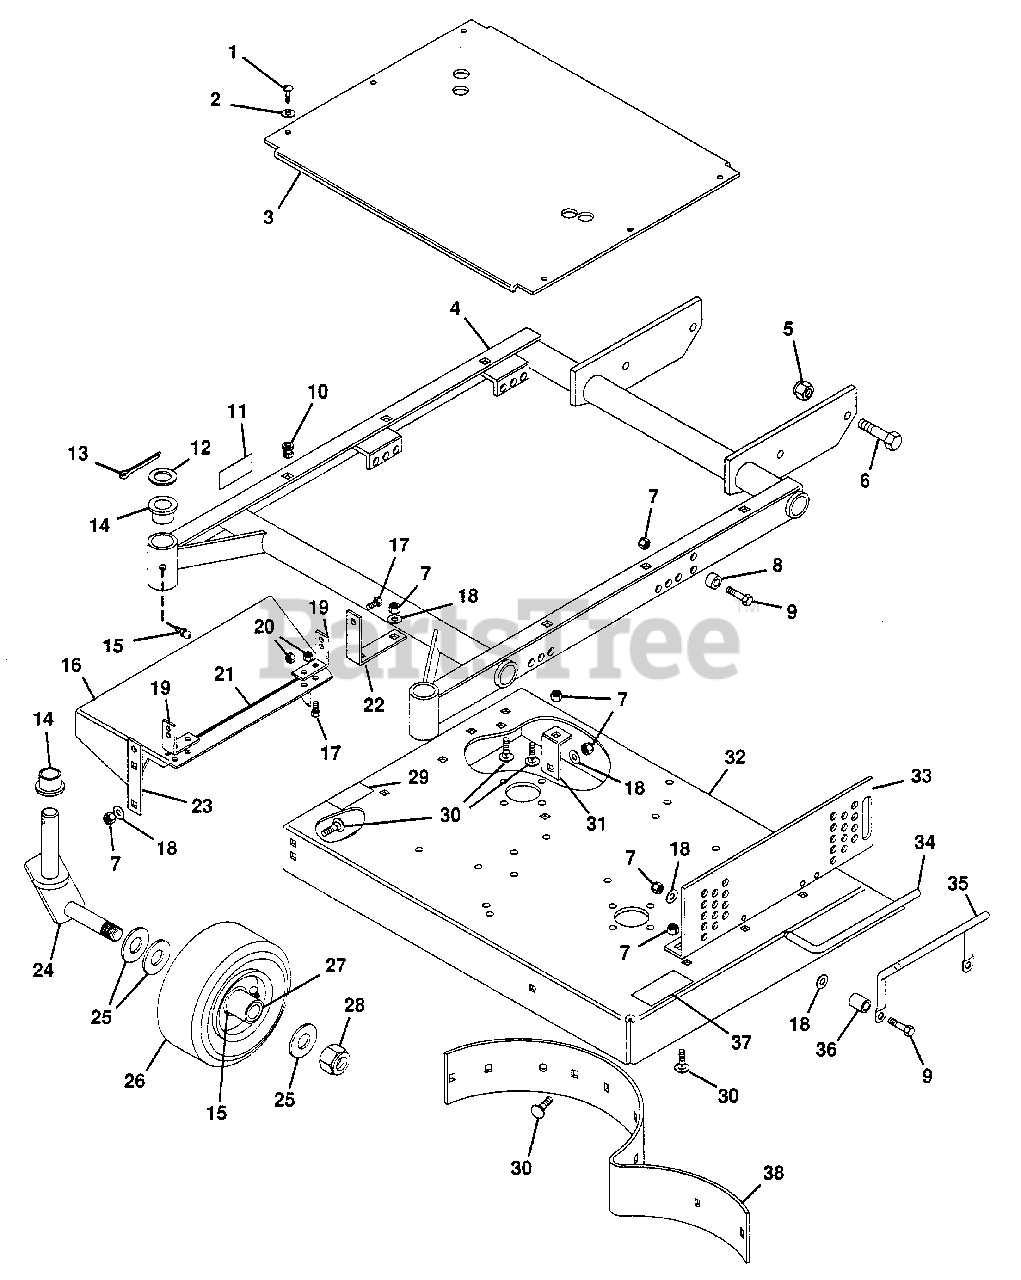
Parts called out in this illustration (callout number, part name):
1	Screw, 1/4-20x.50 Self Tapping
2	Washer, Flat .281x.625x.065
3	Cover, Silkscreen 36" Mower
4	Wldmt, Mower Frame Multi-Mode
5	Nut, Lock 5/8-11
6	Bolt, Hex 5/8-11x1.50
7	Nut, Lock 3/8-16
8	Bushing, St. .391x.621x.676 Stl.
9	Bolt, Hex 3/8-16x1.50
10	Grommet, Plastic
11	Decal, Danger Hand
12	Race, Bearing Thrust
13	Pin, Cotter .187x1.50
14	Bushing, Flange Nylon
15	Fitting, Lube 1/4-28
16	Chute, Discharge
17	Bolt, Hex 5/16-18x.75
18	Washer, Flat .406x.812x.065
19	Bracket
20	Nut, Lock 5/16-18
21	Decal, Width of Cut
22	Bracket
23	Bracket
24	Weldment, Caster Fork
25	Washer,Flat .812x1.496x.134
26	Wheel, Gauge
27	Bearing, Gauge Wheel
28	Nut, Lock 3/4-10
29	Decal, Warning Eye
30	Bolt, 3/8-16x1.00 Rd Hd Sq Nk
31	Bracket
32	Weldment, 36" R.D. Deck
33	Bracket, Mower Side Support L.H.
33	Bracket, Mower Side Support R.H.
34	Pin, Mower Locking
35	Handle
36	Bushing
37	Decal, Danger Foot
38	Scroll
